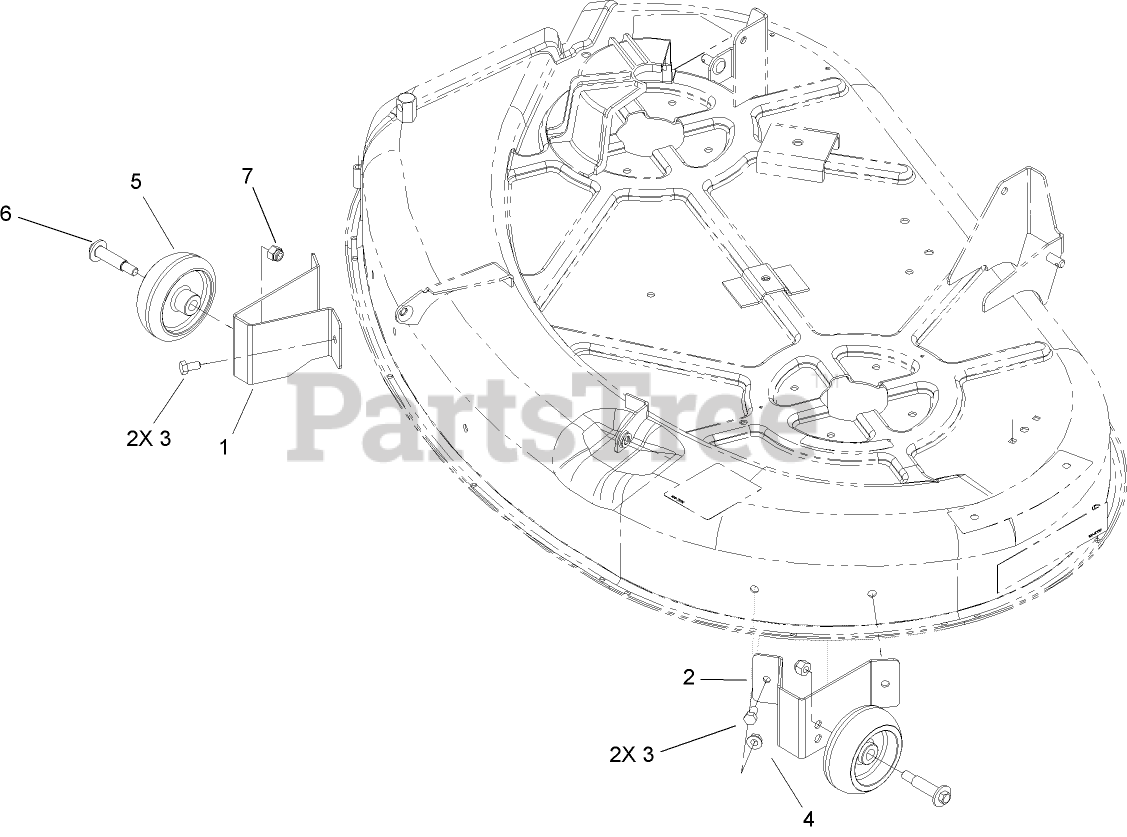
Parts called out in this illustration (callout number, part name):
1	BRACKET-GAGE WHEEL, FRONT (RH)
2	BRACKET-GAGE WHEEL, FRONT (LH)
3	SCREW-HH
4	NUT-HF
5	WHEEL-GAGE
6	SCREW-SHOULDER, HWH
7	NUT-LOCK, NI
